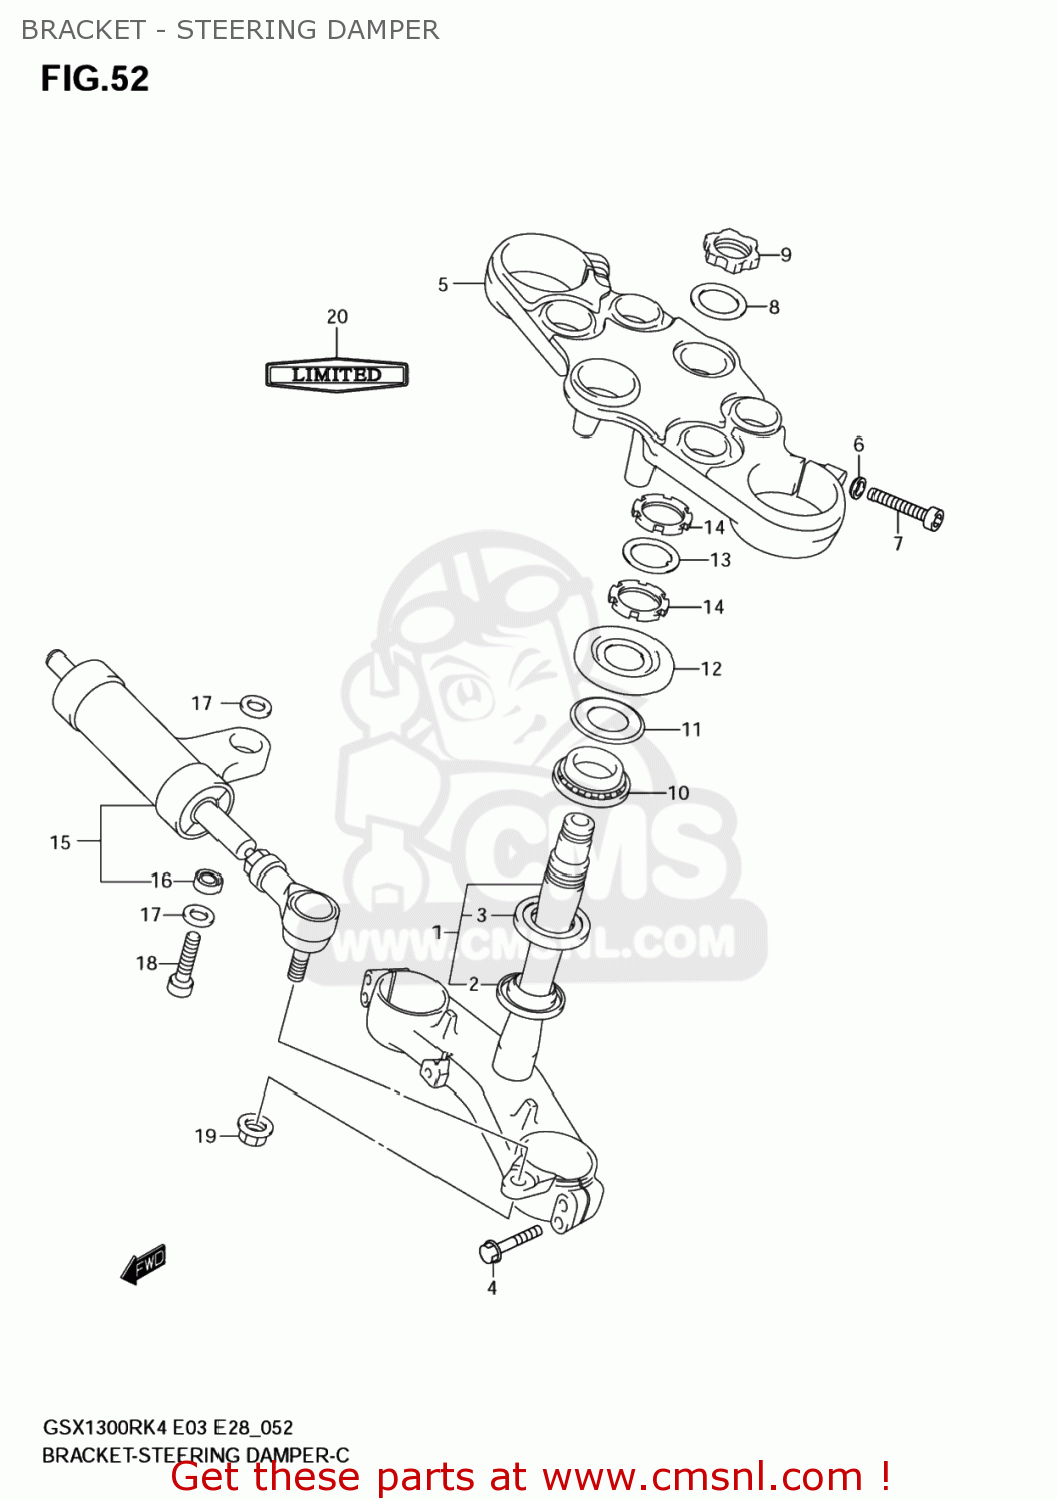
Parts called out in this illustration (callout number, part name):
1	BRACKET,FR FORK UNDER
2	SEAL,STEERING LWR
3	BEARING(30X55X17)
4	BOLT
5	BRACKET,FR FORK UPR
6	WASHER
7	BOLT
8	WASHER,STEM HEAD(24.5X34X1.6)
9	NUT
10	BEARING(30X55X17)
11	SEAL,STEERING LWR
12	COVER,STEERING UPR
13	WASHER,STEERING STEM
14	NUT,STEERING STEM
15	DAMPER ASSY,STEERING
16	BEARING(8X17.5X11)
17	SEAL,PILLOW BALL,DUST
18	BOLT
19	NUT
20	EMBLEM,LIMITED
